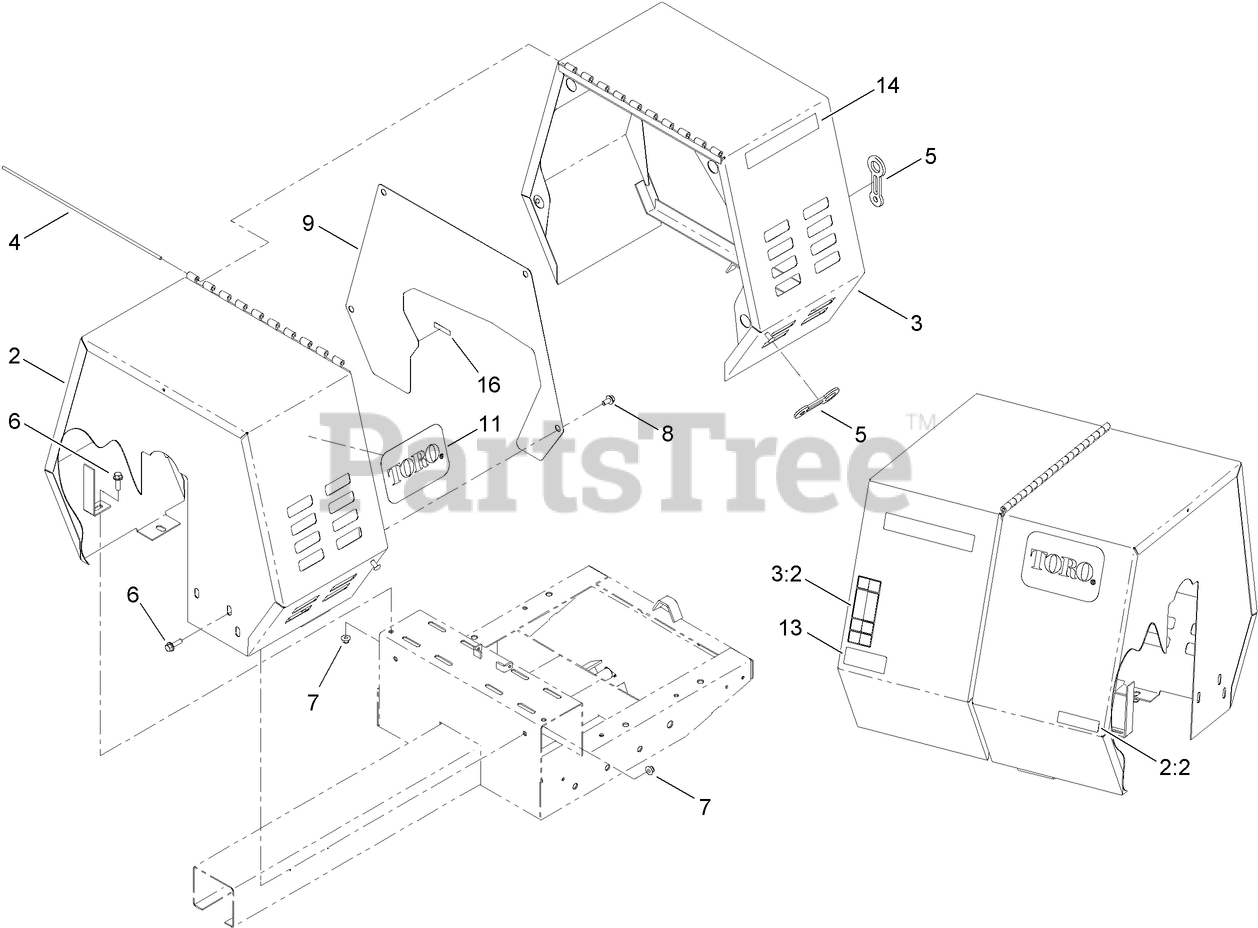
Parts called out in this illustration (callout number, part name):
2	STATIONARY COWL ASM
2:2	DECAL-ARRESTER, SPARK
3	MOVABLE COWL ASM
3:2	DECAL-WARNING
5	LATCH-RUBBER
6	SCREW-HHF
7	NUT-HF, NI
8	SCREW-HWH
9	PLATE-GUARD, BELT
11	DECAL
14	DECAL-MM-650E
16	DECAL-GREASE
